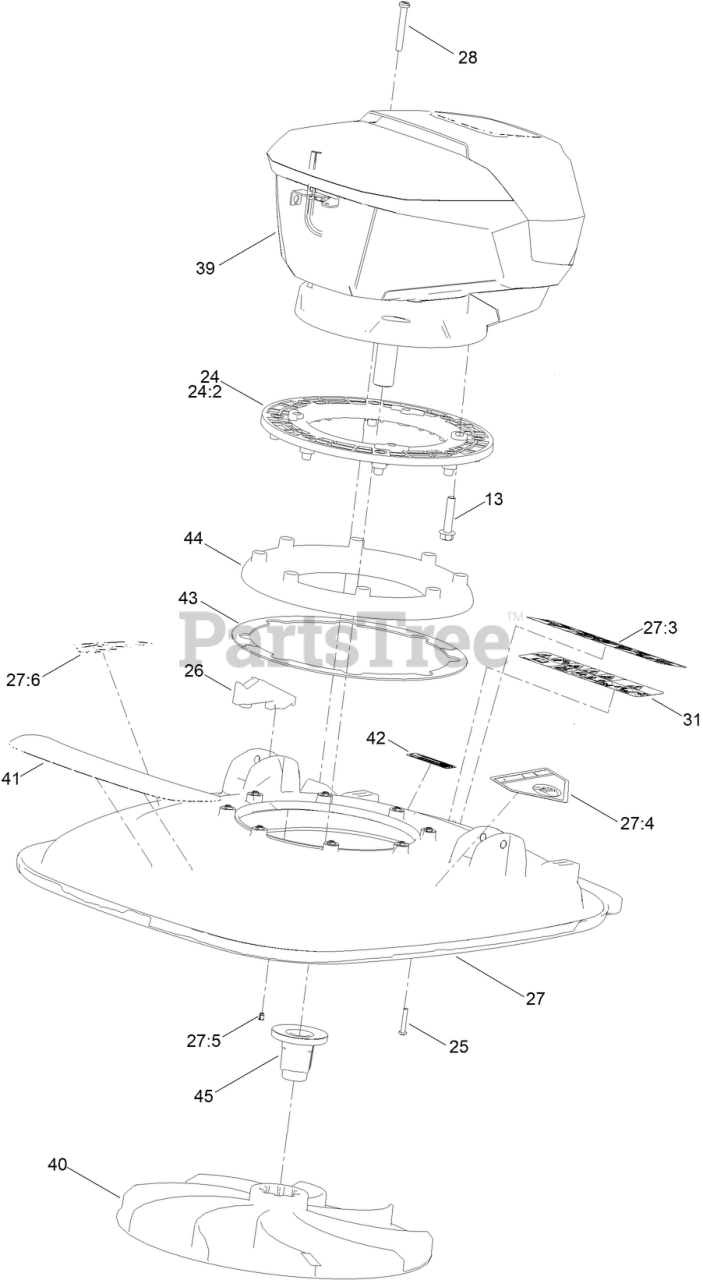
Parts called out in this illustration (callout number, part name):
13	SCREW-TAPTITE
24	FRAME-ENGINE
24:2	INSERT-BRASS
25	SCREW-PPH
26	BRACKET
27	DECK ASM
27:3	DECAL-WARNING
27:4	DECAL-DANGER
27:5	INSERT
27:6	DECAL-DANGER
28	SCREW
31	DECAL - WARNING, 60V EHOVERPRO
39	MOTOR MODULE
40	IMPELLER
41	DECAL - FRONT 60V EHOVERPRO 450
42	DECAL-PROP 65, SHORT, TRILINGUAL
43	GASKET-FRAME
44	BELL MOUTH
